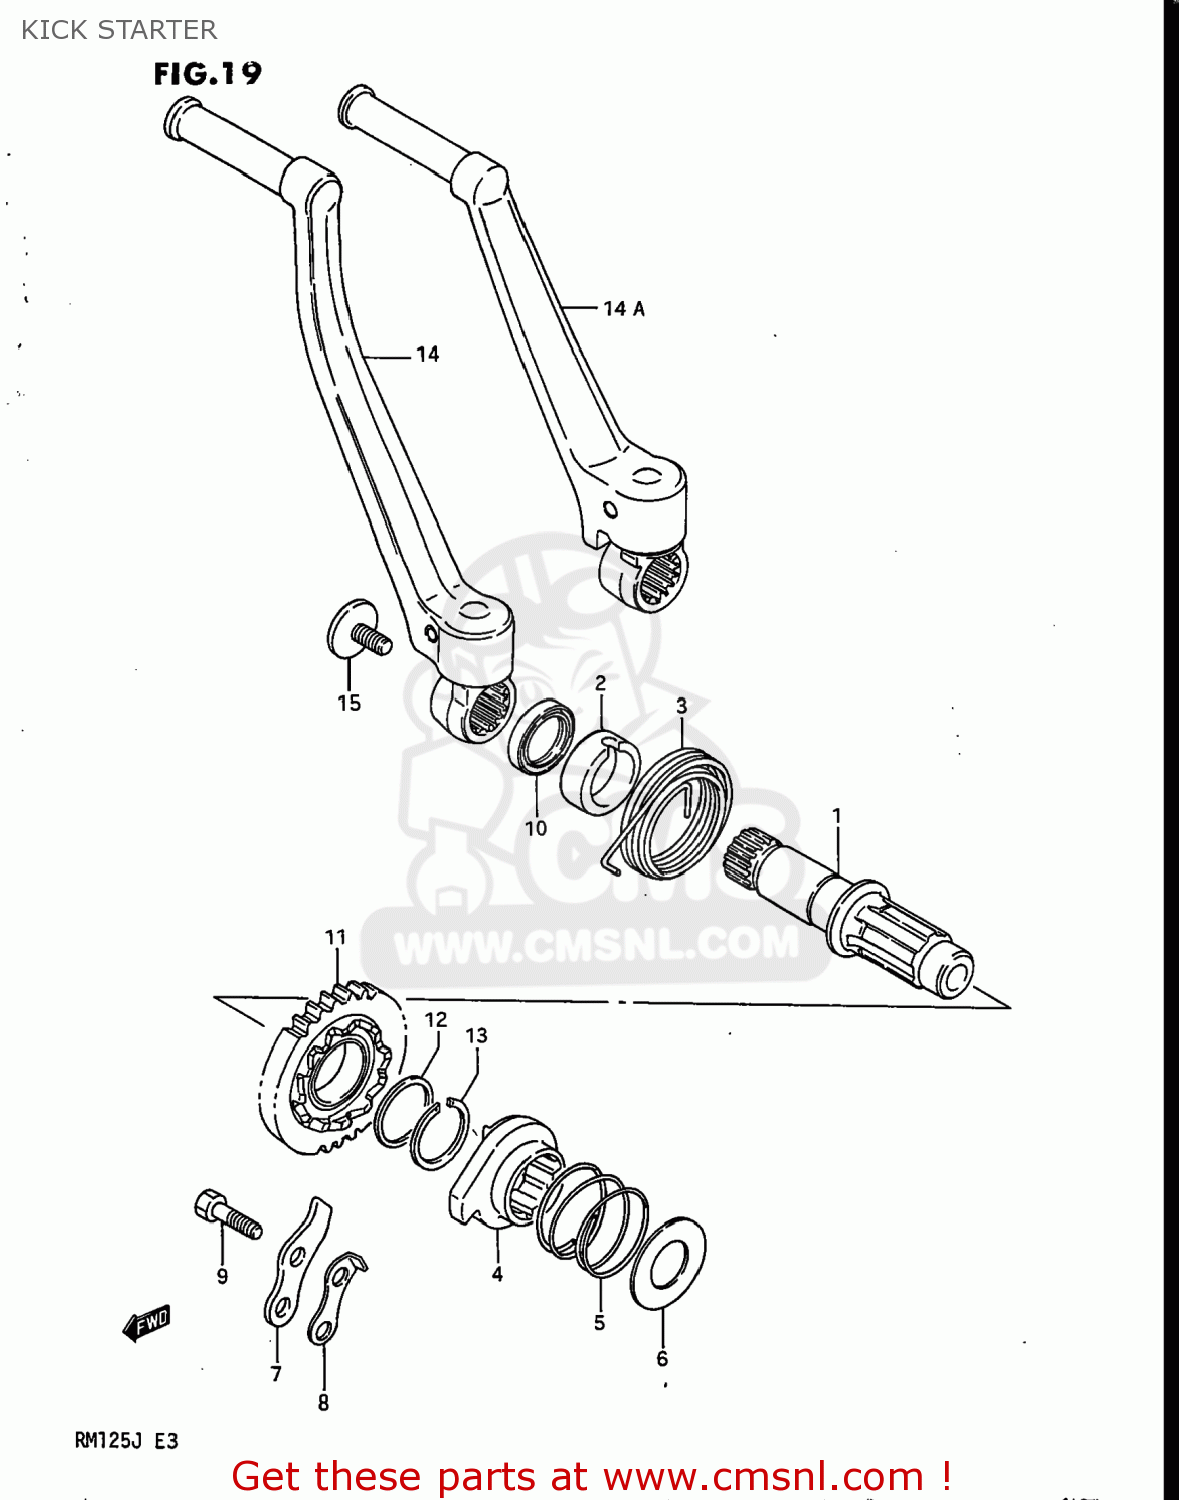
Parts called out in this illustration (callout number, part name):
1	SHAFT,KICK STARTER
2	GUIDE,KICK STARTER SHAFT
3	SPRING
4	STARTER,KICK
5	SPRING
6	WASHER
7	GUIDE,KICK STARTER
8	STOPPER,KICK STARTER
9	BOLT
10	SEAL,OIL(20X27X5)
11	GEAR,KICK STARTER DRIVE
12	SHIM
13	CIRCLIP
14	LEVER ASSEMBLY,KICK STARTER
14A	LEVER ASSEMBLY,KICK STARTER
15	BOLT
